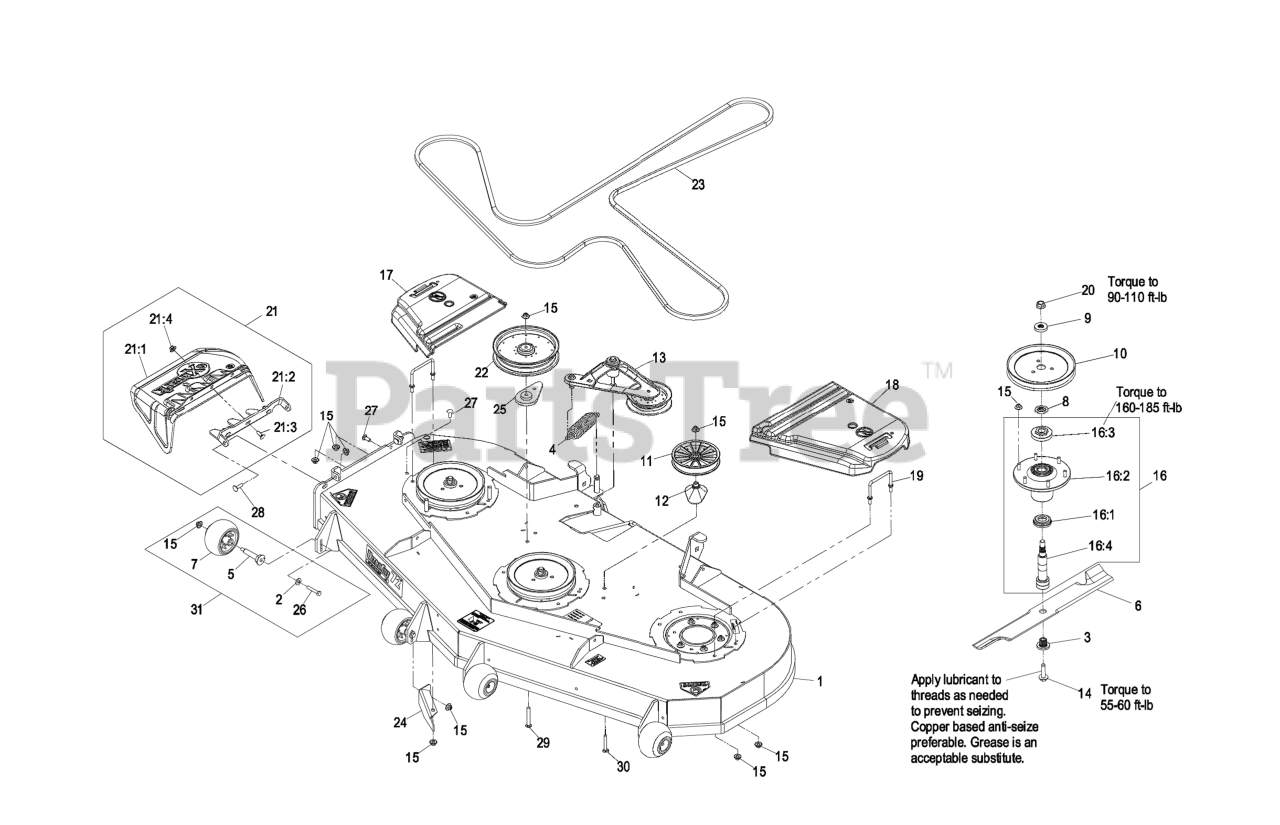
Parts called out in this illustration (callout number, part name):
1	DECK W/ DECALS ASM-72
2	WASHER-BELLEVILLE
3	BUSHING,SPLINED
7	ROLLER-SCALP, ANTI
8	SPACER,SPLINED STEPPED
9	SPACER,SPLINED
10	SHEAVE,BLADE DRIVE 9.00
11	PULLEY,IDLER 6"
12	SPACER-PULLEY
14	SCREW,SEMS 1/2-20 X 2.19
15	Nut-Nyloc 3/8-16 Flg
16	ASM,SPINDLE HOUSING
16:1	GUARD,BOTTOM
16:2	ASM,CUTTER HOUSING
16:3	NUT, SPINDLE 7/8-14
16:4	SPINDLE,DOUBLE SPLINE
17	COVER-BELT, RH
18	COVER-BELT, LH
19	WIREFORM-COVER
20	NUT-FLANGE, CENTERLOCK
21	ASM,DISCHARGE CHUTE
21:1	CHUTE,DISCHARGE
21:2	BRACKET,DISCHARGE CHUTE
21:3	SCREW-CARR
21:4	Nut-Nyloc 3/8-16 Flg
22	PULLEY-IDLER
23	BELT-V
24	BAFFLE,DISCHARGE 726
25	SPACER-IDLER
26	SCREW-HH
27	SCREW-CARR
28	Bolt-Carriage 3/8-16 X 1 1/4
29	SCREW-CARR
30	SCREW-CARR
32	Asm, Deck Complete 726
